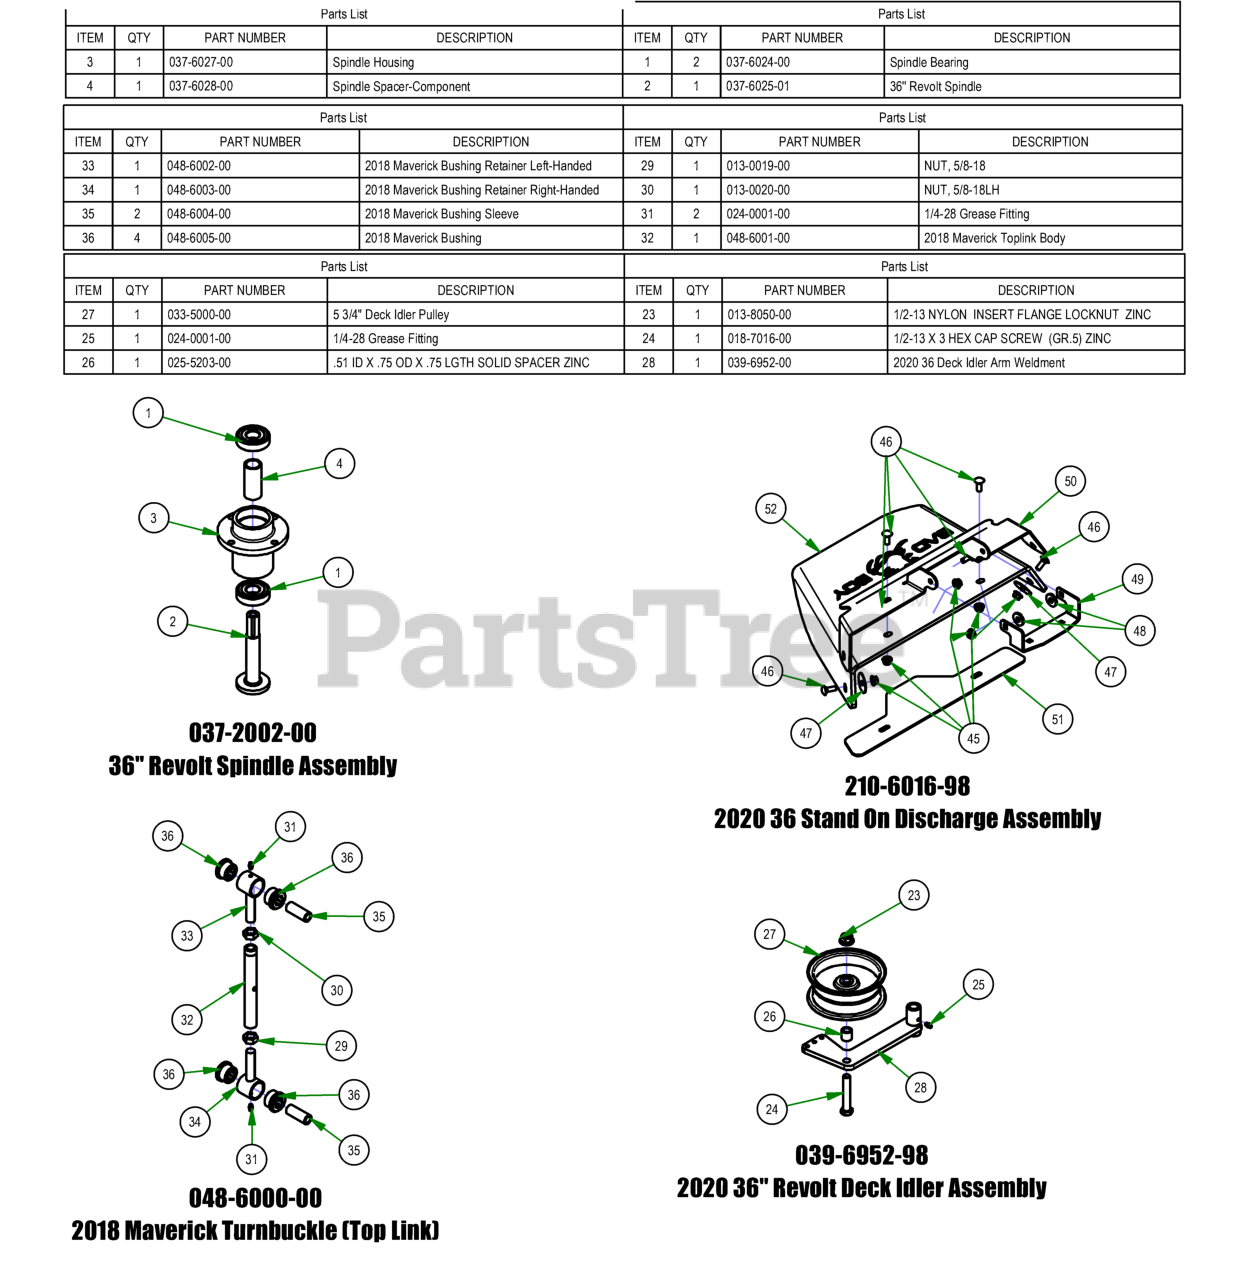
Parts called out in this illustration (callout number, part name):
1	Spindle Bearing
2	36'' Revolt Spindle
3	Spindle Housing
4	Spindle Spacer-Component
45	5/16-18 NYLON INSERT FLANGE LOCKNUT ZINC
46	5/16-18 X 7/8 CARRIAGE BOLT ZINC
47	5/16 FENDER WASHER (1-1/2 OD) ZINC
48	.360 ID X .983 OD X .120 THICK FLAT WASHER NYLON
49	2020 36 Stand On Chute Hanger
50	Discharge Chute Bracket 48 MZ (Upper)
51	2017 MZ Discharge Chute Bracket-Lower
52	Rubber Discharge Chute MZ (Component)
